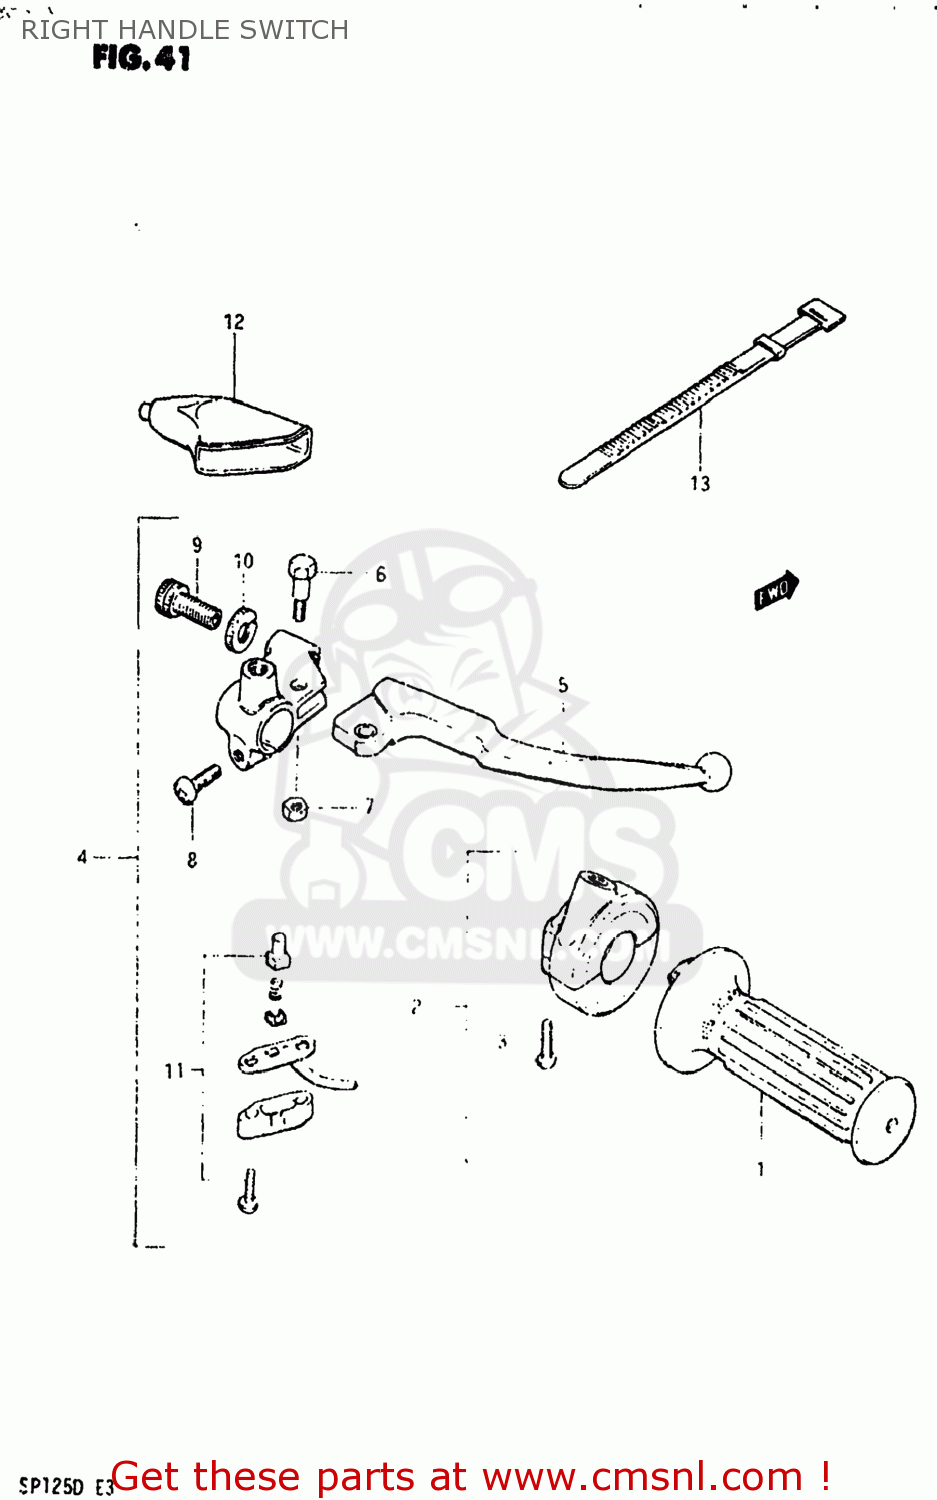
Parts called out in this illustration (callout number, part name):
1	GRIP,THROTTLE
2	CASE ASSY,THROTTLE
3	SCREW 5X20
4	LEVER/SWITCH ASSEMBLY,BRAKE
5	LEVER,BRAKE
6	BOLT,LEVER
7	NUT 6MM
8	SCREW
9	ADJUSTER,CABLE
10	NUT,CABLE ADJUSTER
11	SWITCH ASSEMBLY
12	DUST SEAL,BRAKE/CLUTCH
13	CLAMP(L:120)
